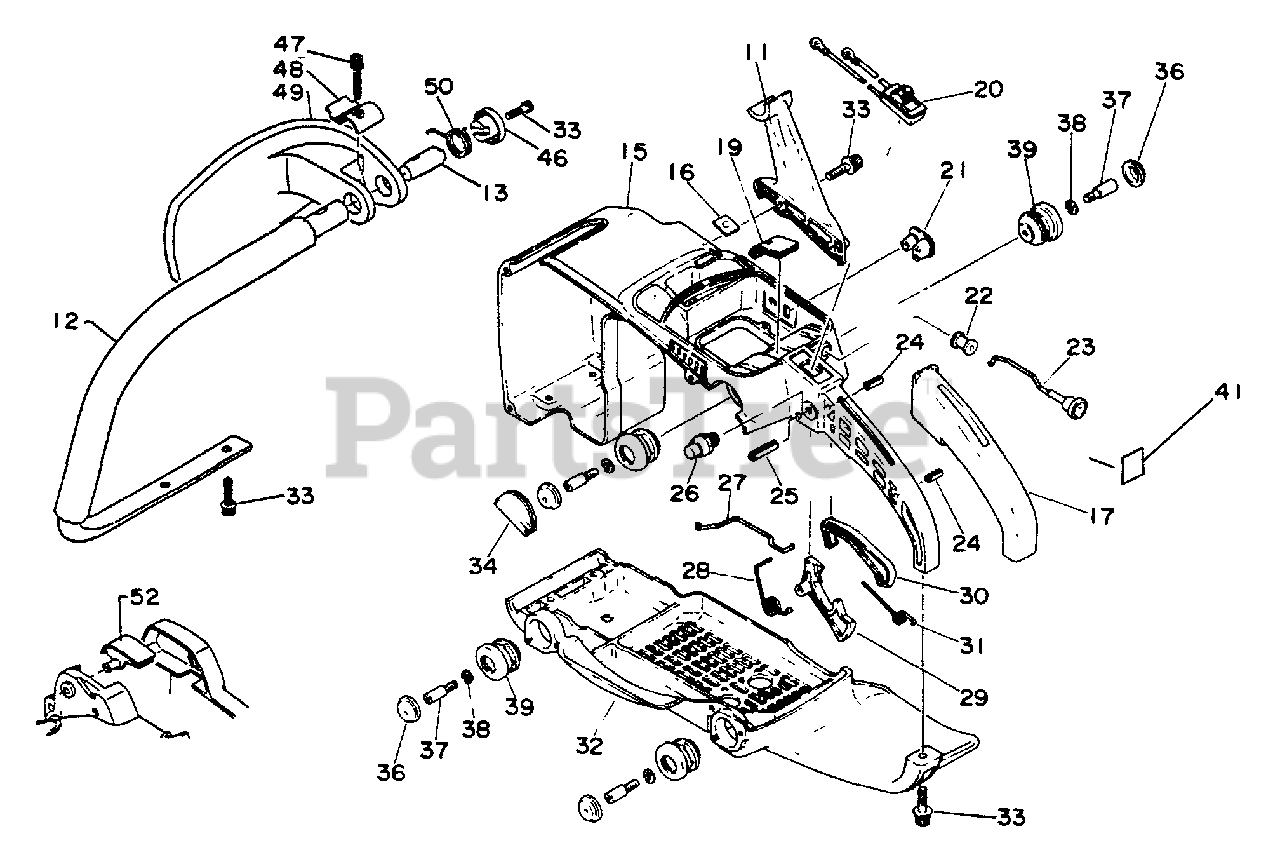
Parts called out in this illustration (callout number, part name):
11	BRACKET, HANDLE - UPPER
12	HANDLE, FRONT
13	SPACER, HANDLE
15	HANDLE - REAR
17	GRIP, HANDLE
19	GROMMET
20	SWITCH, IGNITION
21	GROMMET
22	GROMMET, CHOKE
23	ROD, CHOKE
24	PIN, SPRING 4×13
25	PIN, SPRING 5×25
26	LATCH, THROTTLE
27	ROD, THROTTLE
28	SPRING, THROTTLE RETURN
29	THROTTLE
30	LOCKOUT, THROTTLE
31	SPRING, LOCKOUT RETURN
32	SUPPORT
33	BOLT 5×20
34	COVER, CUSHION
36	CAP, CUSHION
38	WASHER, SPRING 5
39	CUSHION
41	LABEL - CHOKE
46	RETAINER
47	BOLT M5×35
48	STOPPER
49	GUARD
52	COVER
